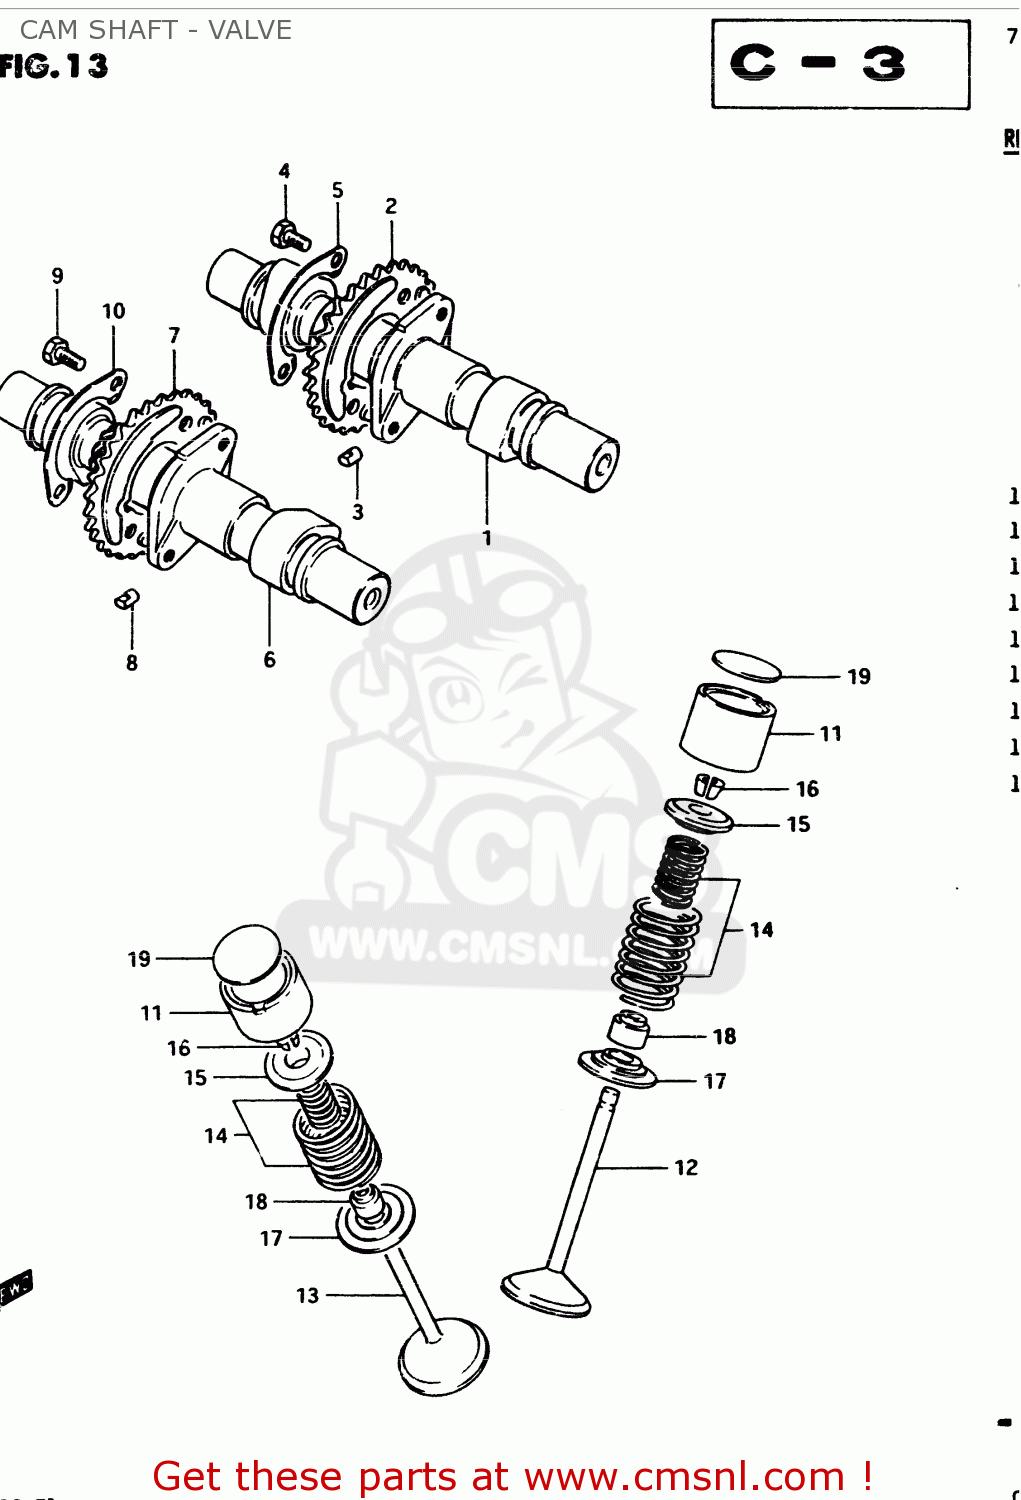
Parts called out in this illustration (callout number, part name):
1	CAMSHAFT,INTAKE
2	SPROCKET,CAMSHAFT
3	PIN,SPROCKET
4	BOLT(6X12.5)
5	WASHER,CAM CHAIN SPROCKET
6	CAMSHAFT,EXHAUST
7	SPROCKET,EXHAUST CAM(NT:30)
8	PIN,SPROCKET
9	BOLT(6X12.5)
10	WASHER,CAM CHAIN SPROCKET
11	TAPPET,INTAKE
12	VALVE,INTAKE
13	VALVE,EXHAUST
14	SPRING SET,VALVE
15	RETAINER,VALVE SPRING
16	COTTER VALVE
17	SEAT,VALVE SPRING
18	SEAL,OIL(7X14.4X9)
19	SHIM,TAPPET
